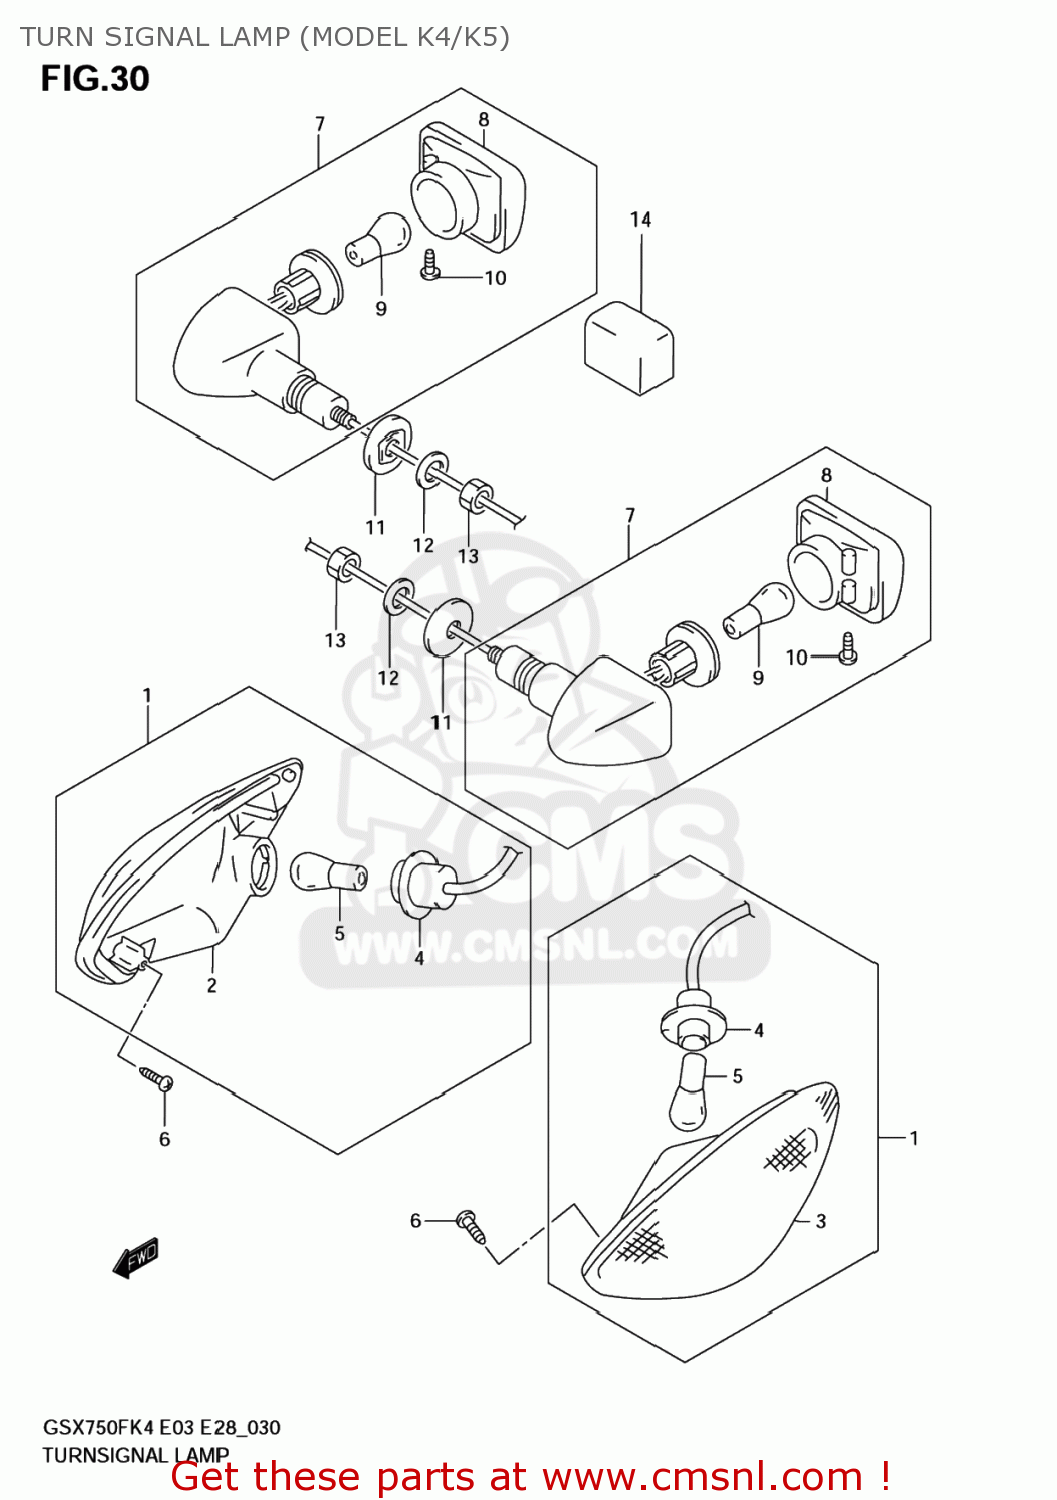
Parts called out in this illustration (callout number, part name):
1	LAMP ASSY,FR TURN SIGNAL,R
2	LAMP UNIT,R
3	LAMP UNIT,L
4	SOCKET & CORD
5	BULB(12V21W)
6	SCREW
7	LAMP ASSY,RR TURNSIGNAL,R
8	LAMP UNIT
9	BULB(12V21W)
10	SCREW
11	SPACER,RR TURNSIGNAL
12	WASHER(10.5X30X2.3)
13	NUT
14	RELAY ASSY,TURNSIGNAL LAMP
